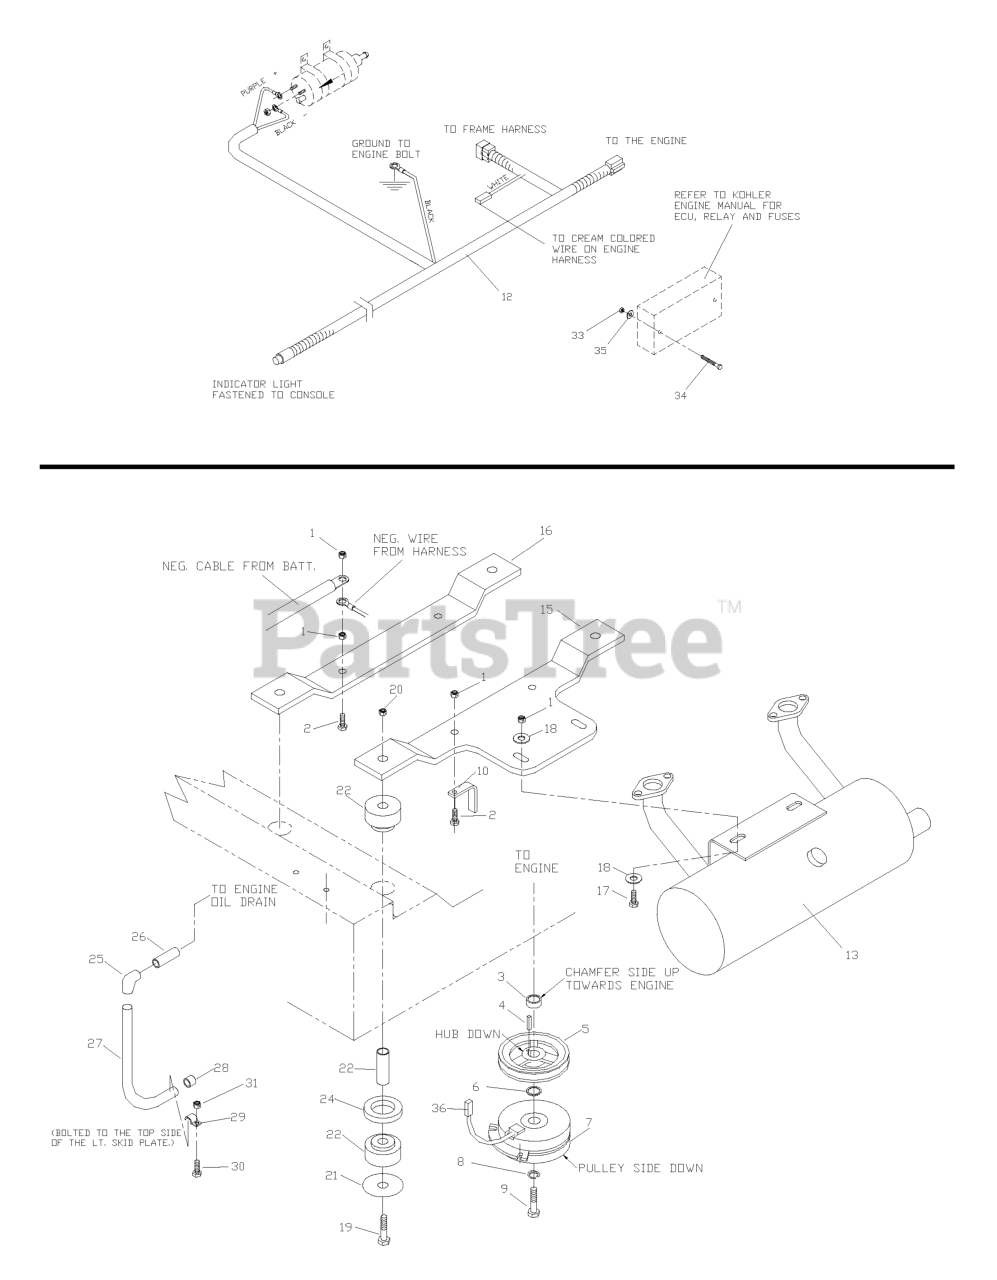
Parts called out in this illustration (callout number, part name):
1	NUT 5/16C CENTERLOCK
2	HCS 5/16C X 1 3/4
3	SPACER .70"
4	KEY 1/4 SQ X 1.0
6	SPACER .508"
7	ELECTRIC CLUTCH W/CABLE
8	7/16 LOCKWASHER
9	BOLT 7/16F X 2 1/2
10	CLUTCH TIE DOWN
12	WIRE HARNESS - EFI
13	MUFFLER EFI KOHLER GEN II
15	REAR ENGINE MOUNT
16	ENGINE MOUNT
17	HCS 5/16C X 1
18	WASHER 5/16 FLAT
19	HCS 1/2C X 3 1/4
20	NUT 1/2-13 HEX NYLOC ZD
21	ISOLATOR WASHER
24	ISOLATOR SPACER
25	90 DEG.ELBOW 3/8NPT
26	PIPE 3/8 NPT 1-1/2
27	OIL DRAIN HOSE
30	HCS 1/4C X 3/4 HCS
31	NUT 1/4C CENTER LOCK
32	SCREW #10 X 1/2 SELF TAPPING
33	NUT 10-24 NYLOC
34	BOLT 10-24 X 2
35	WASHER #10
36	CLUTCH HARNESS
